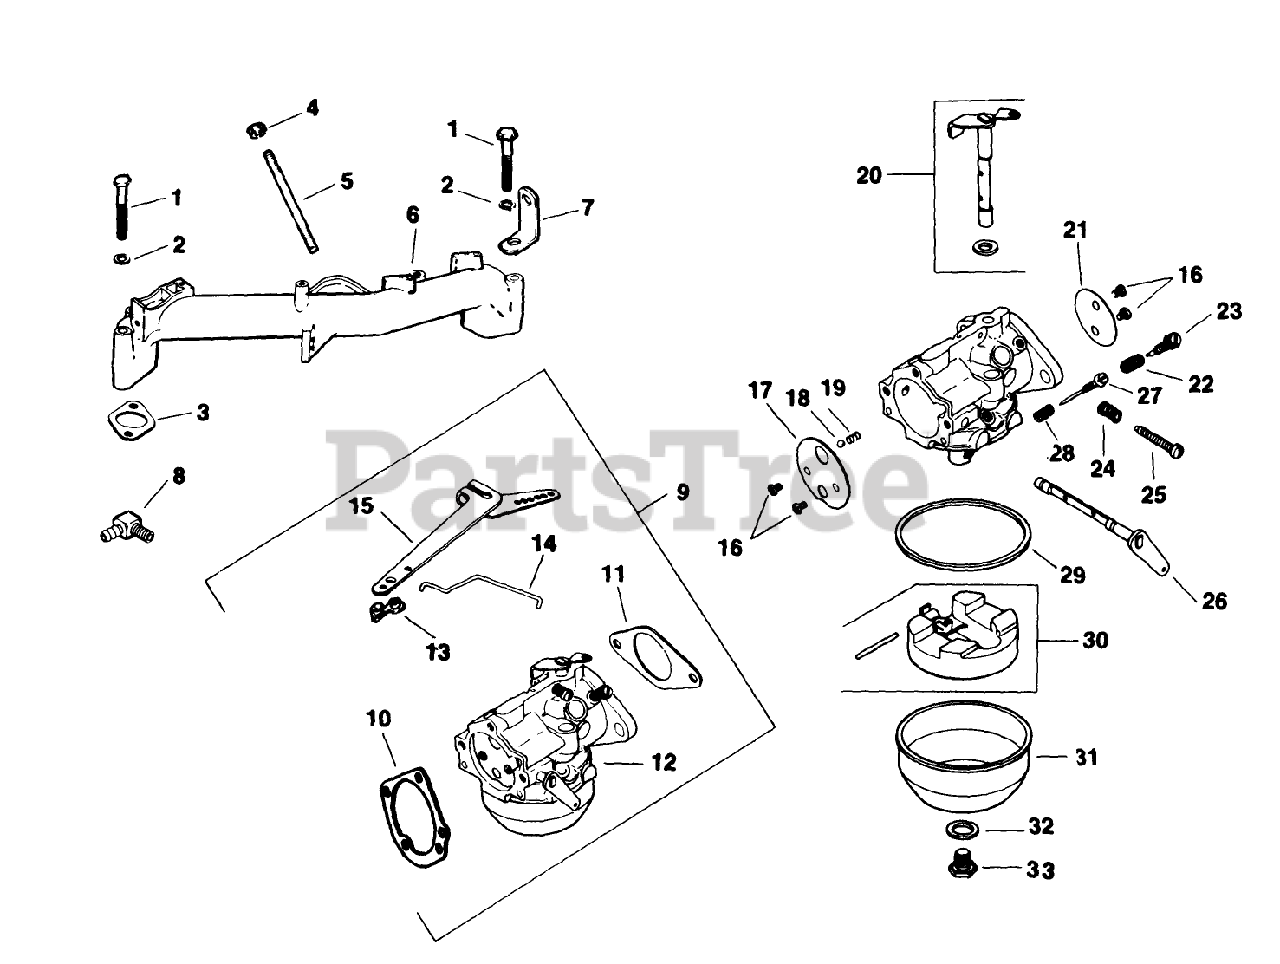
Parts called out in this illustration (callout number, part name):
1	Screw-H.C.
2	Washer
3	Gasket-Intake
4	Nut
5	Stud
6	Manifold-Intake
7	Strap-Lifting
8	Connector-90deg.
9	Kit-Carburetor w/Gasket (Incl. Ref. #10-33)
10	Gasket
11	Gasket
12	Carburetor
13	Bushing
14	Kit-Governor Linkage (Incl. Ref. #13)
15	Arm-Governor
16	Screw-Throttle Plate
17	Plate-Choke
18	Ball-Choke
19	Spring-Choke
20	Shaft-Throttle Lever & Sea
21	Plate-Throttle
23	Valve-Needle
26	Lever-Choke
27	Needle-Main Fuel
29	Bowl-Gasket
30	Kit-Float
32	Gasket-Bowl
33	Screw-Bowl
